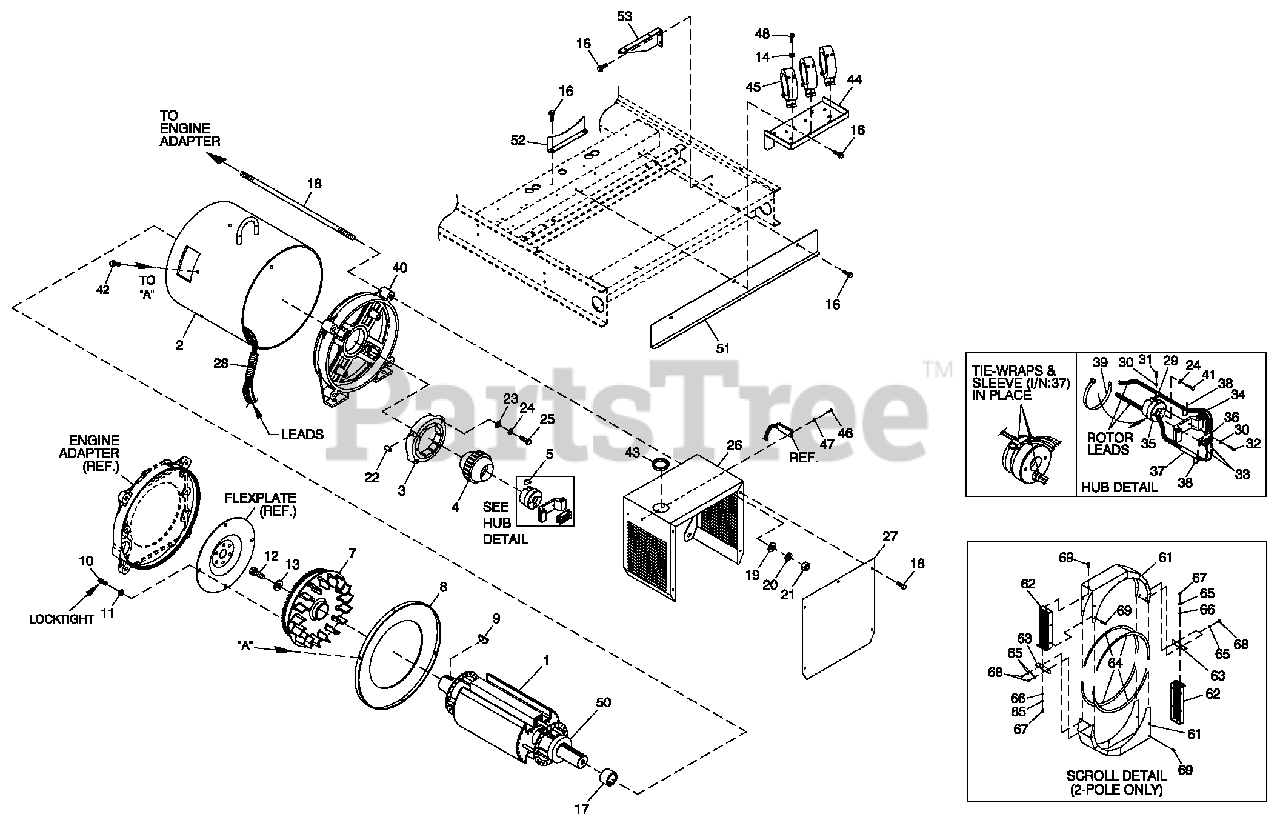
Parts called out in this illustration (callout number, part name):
1	ASSY ROTOR 390 2P 150K BRSHLS
2	ASSY STATOR 390 2P 150K BRSHLS UL
3	EXITER FIELD 2" LG SPD CONN
4	ASSY EXCITER 2.0" STACK 2P
5	KEY SQ 3/8 X 3-1/4 STEEL
7	ASSY FLYWHEEL CPL
8	RING PRESSURE 390 STATOR CAN
9	KEY WOODRUFF #E
10	SCREW SHC M10-1.5X 16 G10.9
11	W ASHER LOCK M10
12	SCREW HHC M 16-2.0X 45G 8.8
13	W ASHER FLAT .688 ID X 3.25 OD
14	W ASHER FLAT 1/4-M6 ZINC
15	W ASHER LOCK M6-1/4
16	SCREW THF M6-1 X 16 N WA Z/JS
17	COLLAR SLIP FIT 390 MM
18	STUD M 14-2.0X 760 G5 ZINC
19	WASHER FLAT M14
20	W ASHER LOCK M14
21	NUT HEX M 14-2.0G 8Y E LC H R
22	PIN DOWEL 1/2 X 1-1/4
23	W ASHER FLAT M12
24	W ASHER LOCK M12
25	SCREW HHC M12-1.75 X 80 G10.9
26	SHIELD ALT EXCITER 390
27	COVER EXCITER SHIELD
28	CONDUIT FLEX 1.25" ID
29	CLAMP VINYL .312 X .203 Z
30	W ASHER SHAKEPROOF INT #8
31	SCREW HHM # 8-3 2 X 3 /8
32	SCREW HHM # 8-3 2 X 7 /8
33	LUGRT-ANG #10/10-12
34	BRIDGE SUPPORT DIODE 15"
35	CAP END ROTOR 390MM
36	ASSY BRIDGE RECTIFIER
37	SLEEVING UL#0 .330 ID (3" LG)
38	TIE WRAP UL 3.9" X . 10" BLK
39	TIE WRAP UL 17.7 X .35 BLK HT
40	REAR BEARING CARRIER CPL
41	SCREW HHC M12-1.75 X 60 G10.9
42	SCREW 1/4-20 X 5/8" TAPTITE SS
43	BUSHING SNAP SB-2.5-31
44	MOUNT CT'S 5.4L 100KW
45	TRANSFORMER
46	SCREW PHTT # 6 -3 2 X 1 /2 ZYC
47	W ASHER LOCK #6
48	SCREW HHC M 6-1.0X 20 G8.8
49	NUT HEX M 6 X 1.0 G 8Y E L CHR
50	BEARING BALL 6212 SEALED
51	SHROUD LOW ERALTERNATOR EXCITR
52	SHROUD CENTER ALTERNATR EXCITR
53	SUPPORT CONBOX TRANSFER SWITCH
60	ASSY SCROLL 390 X 60MM CPL
61	SHROUD ALT SHEET METAL CPL 2P
62	SCREEN, 390 SAE ALT 60MM WIDE
63	BRACKET SAE SCROLL TENSIONER
64	VINYL TRIM 1/8" GAP
65	WASHER, SPLIT 1/4"-M6
66	W ASHER FLAT 1/4ZINC
67	SCREW HHC M6-1.0 x 2 5 LG
68	SCREW HHC M 6-1.0X 16 G8.8
69	SCREW SWAGE 1/4-20 X 1/2 Z/YC
